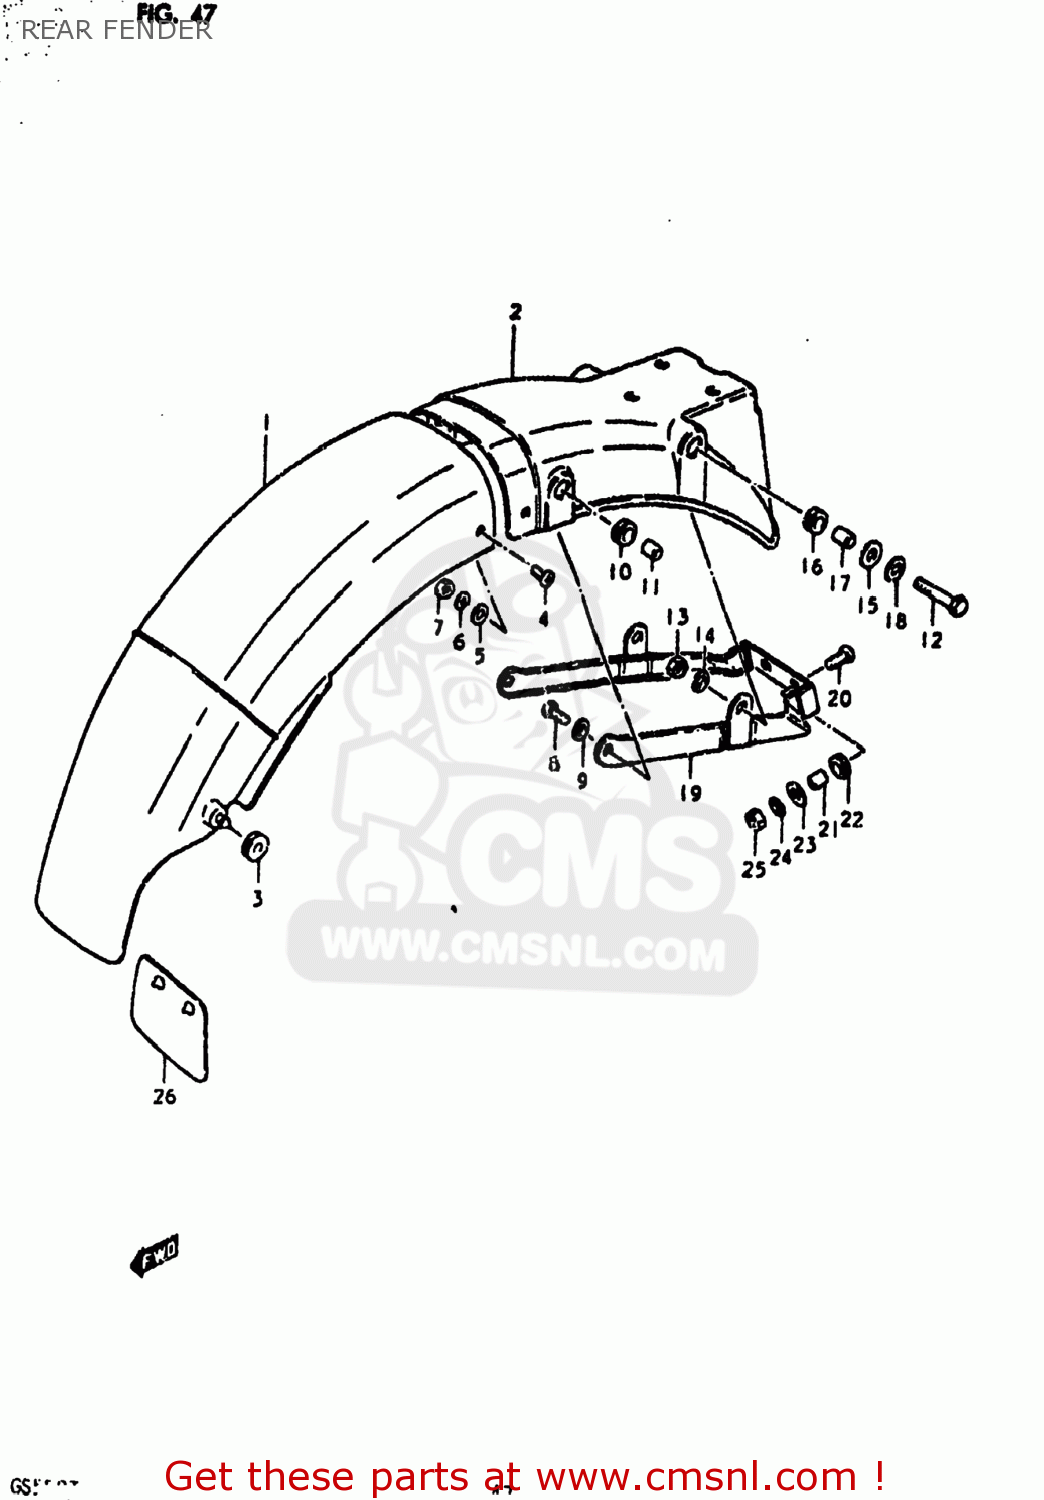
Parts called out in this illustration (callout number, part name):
1	FENDER,REAR
2	BODY,REAR FENDER,REAR
3	CUSHION
4	SCREW
5	WASHER (5.5X16X1.2)
6	LOCK WASHER
7	NUT
8	BOLT
9	LOCK WASHER
10	CUSHION
11	SPACER(6.1X9X7.5)
12	BOLT
13	NUT
14	LOCK WASHER
15	WASHER(8.5X26X1.2)
16	CUSHION
17	SPACER (8.2X12X7.5)
18	WASHER
19	REINFORCEMENT,REAR FENDER
20	SCREW
21	SPACER (6.1X9X9)
22	CUSHION
23	WASHER(6,5X22X1.6)
24	LOCK WASHER
25	NUT
26	GUIDE,RR FENDER MUD
